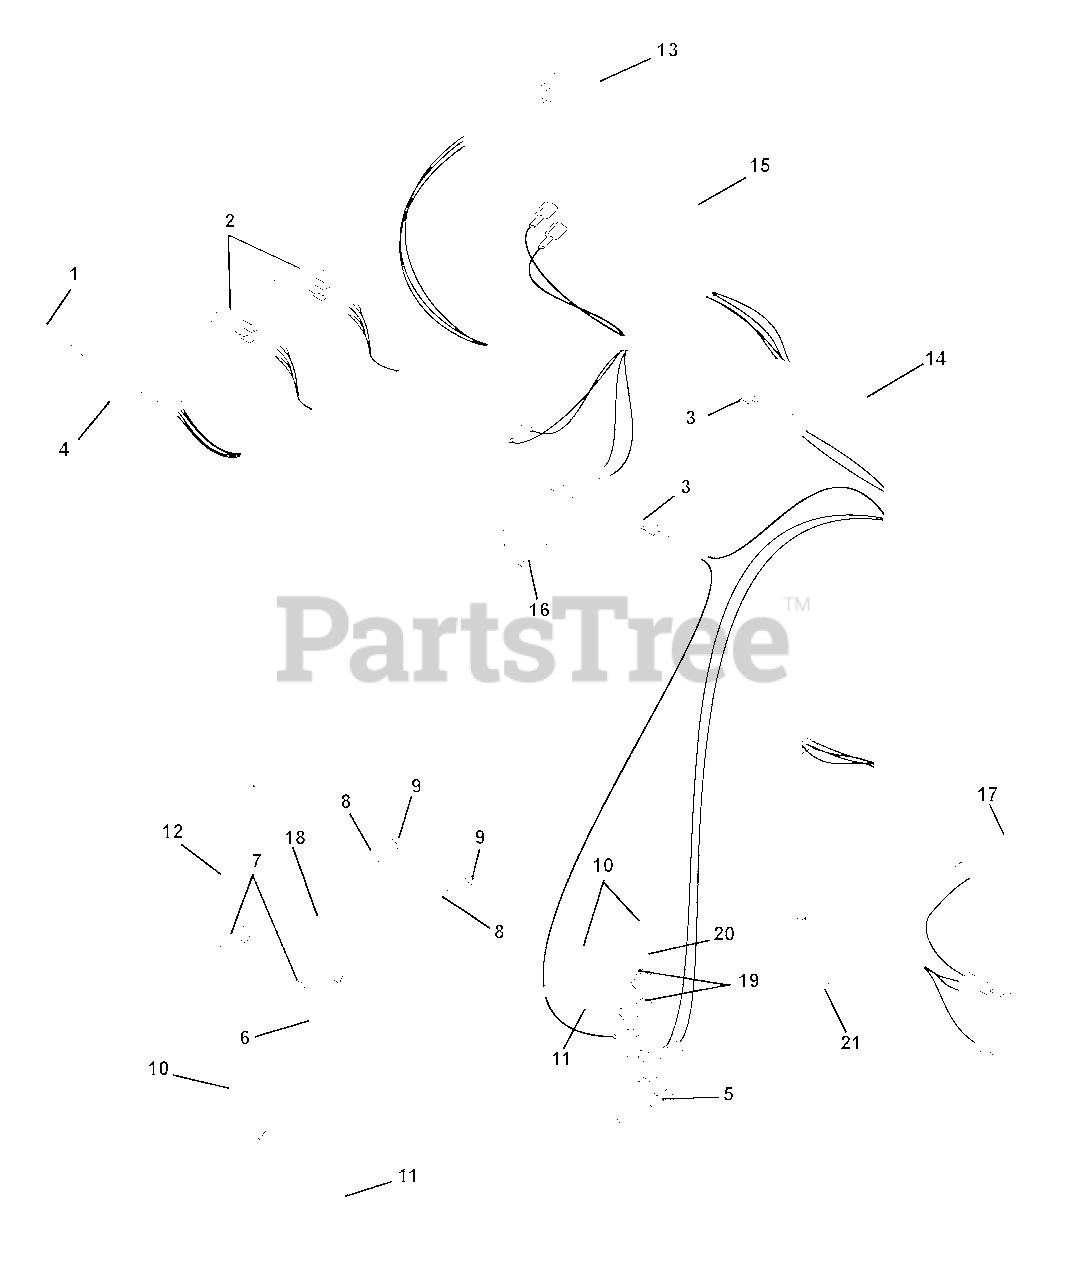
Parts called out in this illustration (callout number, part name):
1	Key with Cap
2	Relay
3	Fuse, 30 AMP
4	Key Switch
5	Solenoid
7	Bolt, Hex .25-20 x .75 Grade 5
8	Washer, Flat Steel .281 x .62 x .065
9	Nut, Keps .250-20
10	Boot, Eyelet Terminal
11	Starter Cable 13"
12	Ground Cable
13	Switch, Clutch With Retainer
14	Harness, Mini Zoom
15	Switch, Double Pole N.O. / N.O.
16	Switch, Snap Mounting (N.O.)
17	Diode, Connector Shell
18	Insulator
19	Washer, Locking .31
20	Nut, Jam .31-24
21	Cable Tie
